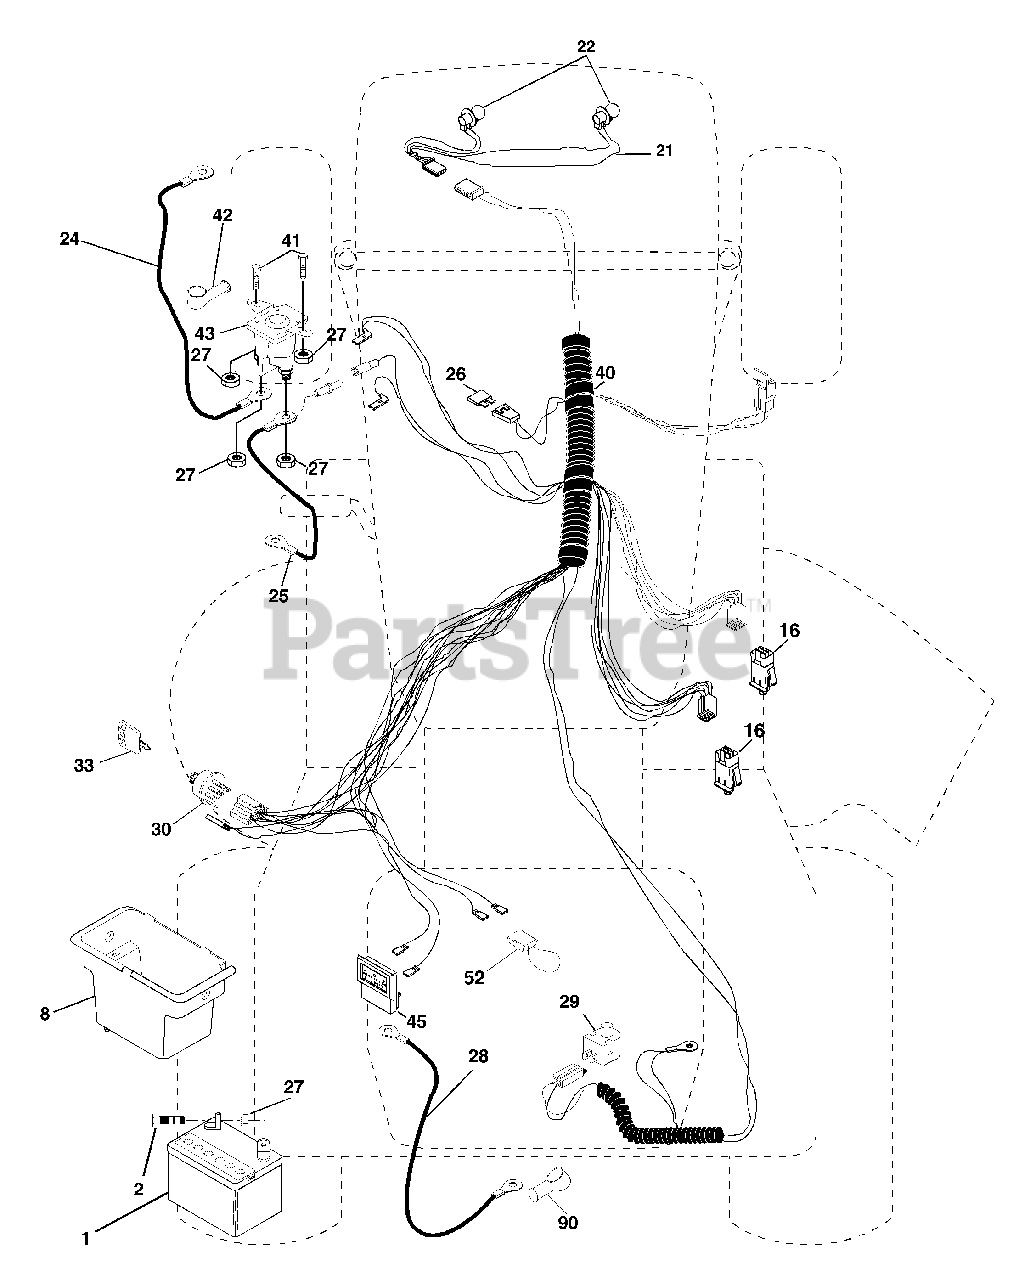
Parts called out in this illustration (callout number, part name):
1	Battery
2	Bolt Hex Hd 1/4-20unc X 3/4
8	Box Battery Fender
16	Switch Interlock
21	Harness Socket Light with 415J
22	Bulb, Light # 1156
24	Cable Battery
25	Cable Battery 6 Ga Red w/16 wire
26	Fuse 20 Amp
27	Nut Keps Hex 1/4-20 Unc
28	Cable Ground 6ga 12 black
29	Switch Plunger Nc Gray
30	Switch Ign
33	Key Ign Molded Generic
40	Harness Ign
41	Bolt Fin Hex 1/4-20uncx 1/2
42	Cover Terminal Red
43	Solenoid
45	Ammeter Rectangular
52	Protection Loop
90	Cover Terminal Battery
